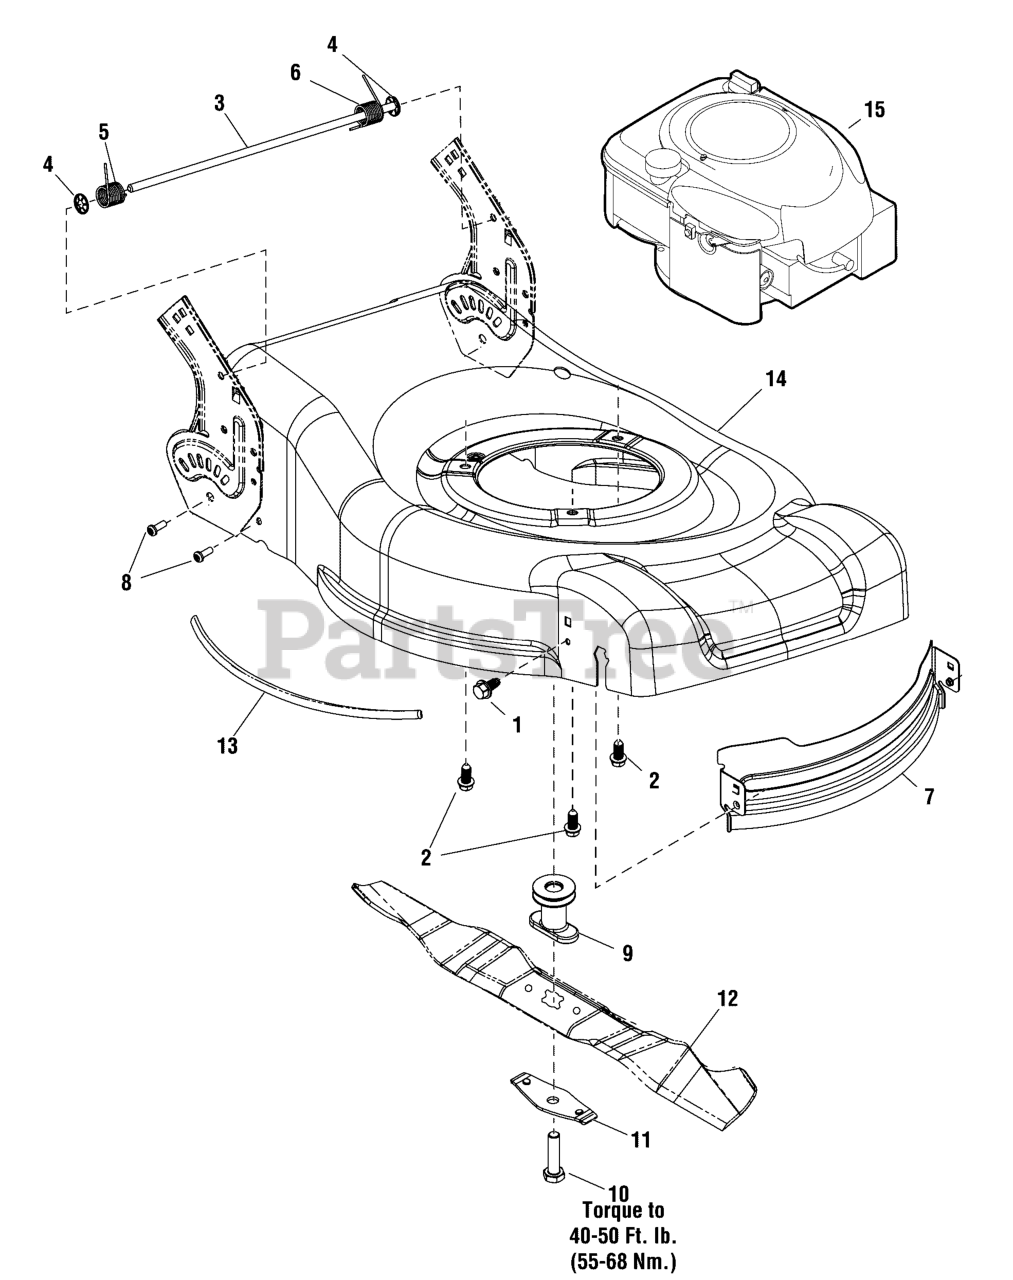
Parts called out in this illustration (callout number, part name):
1	SCREW, M6X1X12
2	SCREW, HXLWSH,TT,SEMS,3/8-16X1
3	ROD, Rear Door
4	RETAINER
5	SPRING, Torsion Rear Door, Right
6	SPRING, Torsion Rear Door, Left
7	BAFFLE, Front
8	SCREW, M6 x 16
9	BLADE ADAPTER ASSEMBLY
10	SCREW, 3/8-24X1.50
11	BLADE WASHER
12	BLADE, 46cm
13	SIDE GUARD, 50cm
14	MOWER HOUSING, Black
15	* ENGINE, Briggs & Stratton 500 Series
